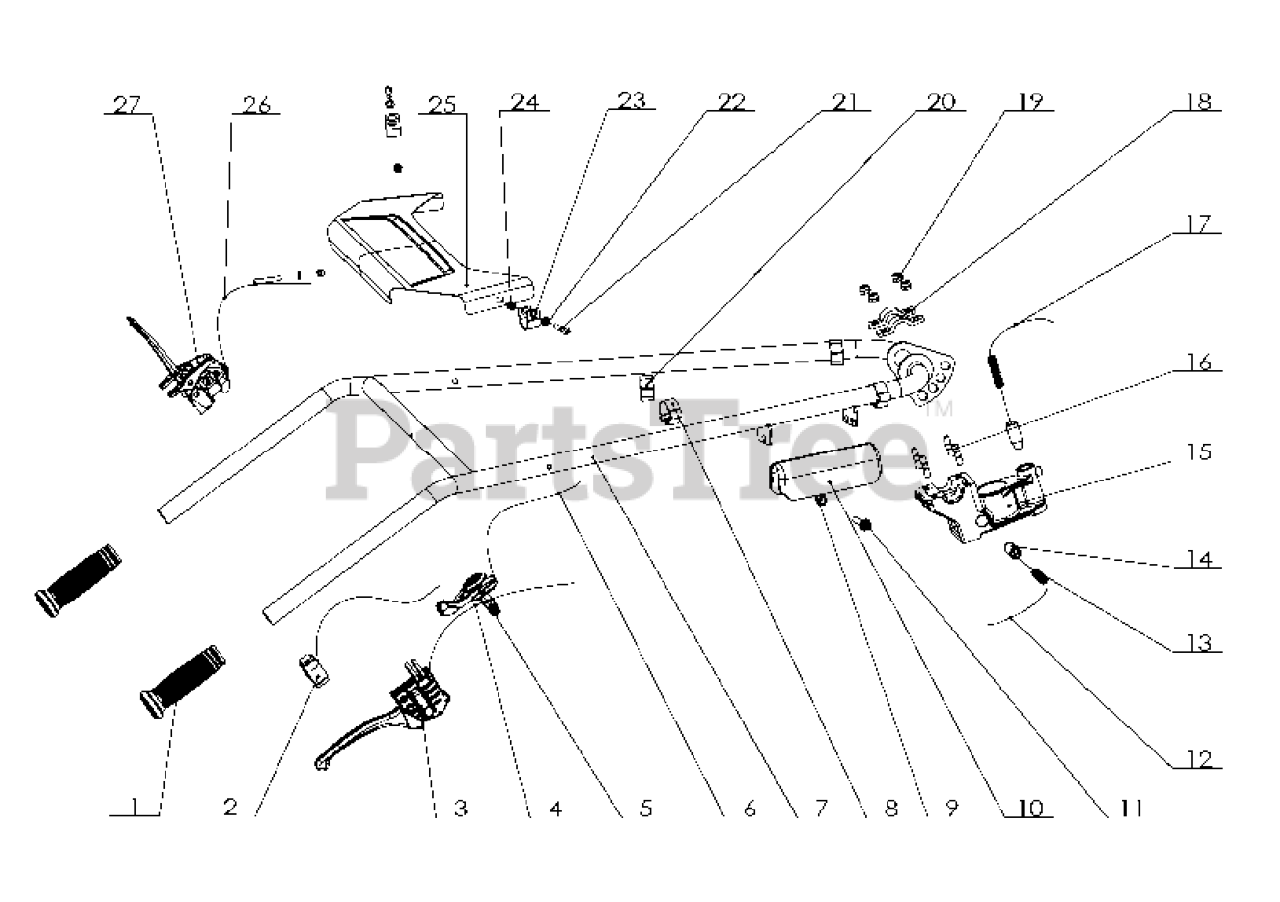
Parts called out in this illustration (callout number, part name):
8	HANDLES
14	STIFFENERS
20	BOXES
